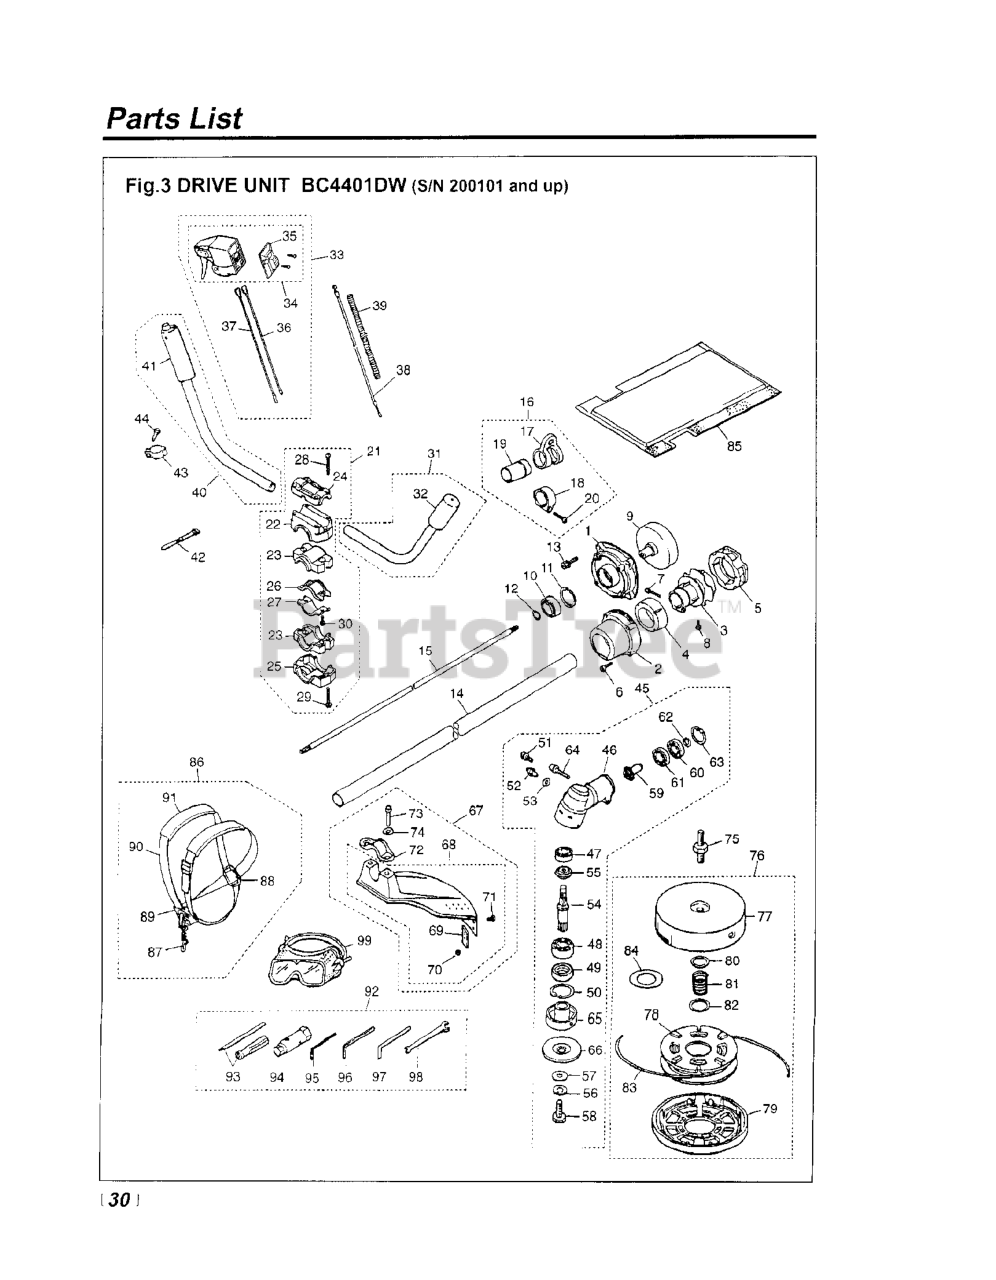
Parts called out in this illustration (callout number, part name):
4	ABSORBER
5	ABSORBER
7	BOLT, M6 x 30
8	BOLT M5 X L10 ALLEN BOLT
9	DRUM
10	BEARING 0600406202
11	SNAP RING
12	RING, SNAP, M15 x 1.0
14	PIPE COMPLETE
16	HANGER ASSEMBLY
21	BRACKET-ASSY
23	ABSORBER
26	CLAMP(A)
27	CLAMP(B)
28	BOLT, M5 x 25
29	BOLT, M5 x 35
33	LEVER COMP.
34	LEVER ASSY
36	CORD (A), BLACK
37	CORD (B), RED
40	HANDLE COMPL, RIGHT
42	BAND(KZC)
45	GEAR CASE ASSY(RPLS T300313000
46	GEARCASE
49	OIL SEAL
51	BOLT M5 X L10 ALLEN BOLT
55	GEAR
58	BOLT M8 X L25 L/H
59	PINION
60	BEARING,10MM ID,26MM OD,8MM W
63	RING,SNAP M26x1.2 RP-318013340
65	HOLDER(A)
66	HOLDER (B)
67	GUARD ASSEMBLY
68	GUARD COMP
75	SHAFT.M8
76	6" TAP HEAD PT100
78	CORD HOLDER
85	PROTECTOR (RPLS 405017110)
89	HANGER COMP
92	TOOL SET
96	Wrench Tool
